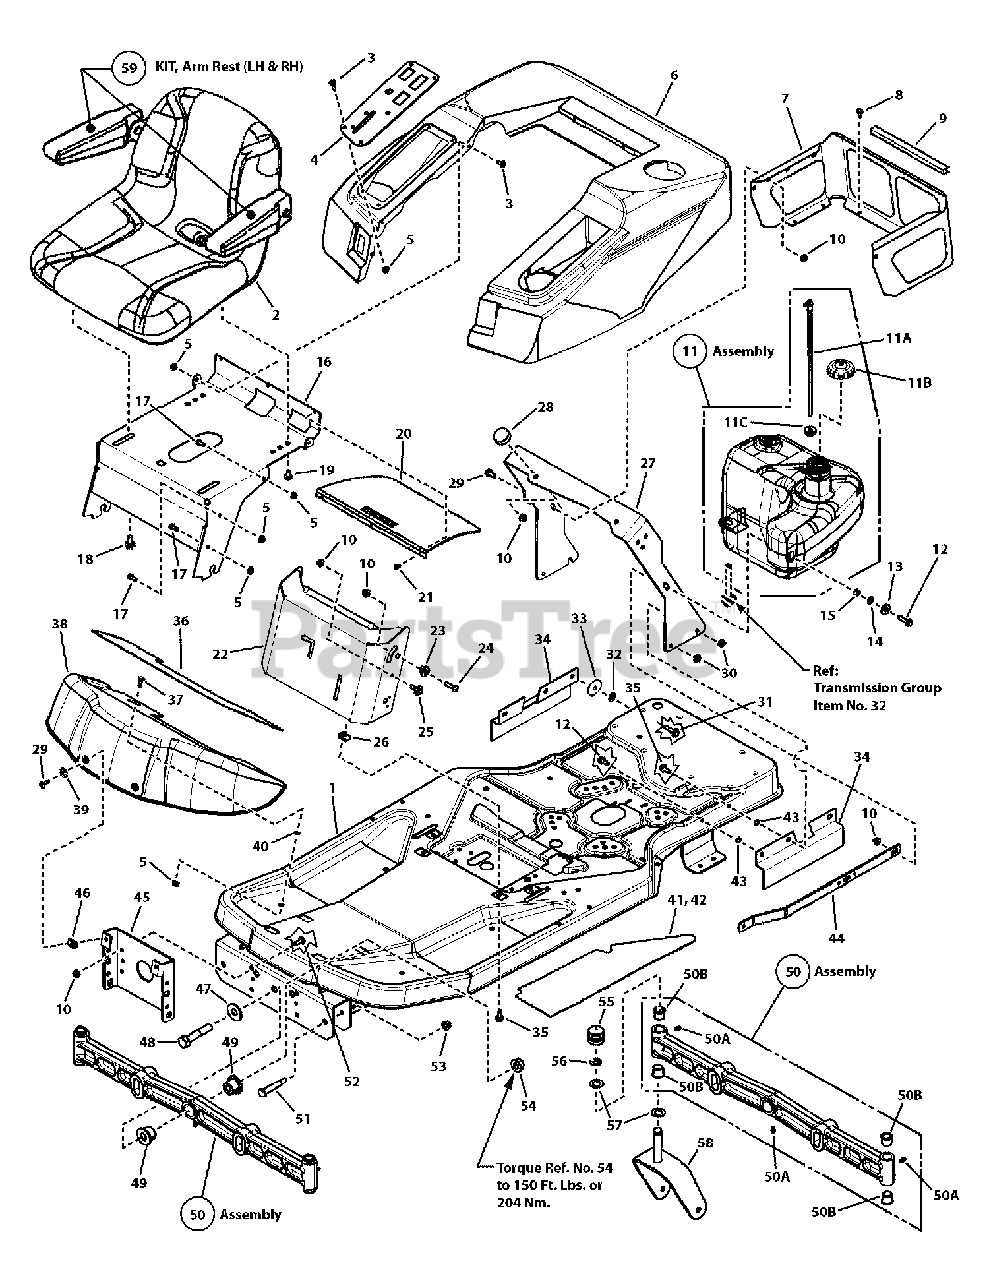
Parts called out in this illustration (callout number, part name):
1	WELDMENT, ZT Frame
2	ASSEMBLY, Seat w/Arm Rests, ZTR
3	SCREW, 1/4-20 x 3/4" Truss Head Torx, Black
4	PLATE, Control, Choke-A-Matic
5	NUT, 1/4-20 Hex Flange Nyloc, Black
6	SEAT DECK, Red Poly, ZTS - Red
7	BRACKET, Rear Shroud, ZTR, Black
8	SCREW, 1/4-20 x 1/2" Hex Washer Head Screw Black (Taptite)
9	TRIM, 8"
10	NUT, 5/16-18 Hex Flange Lock, Small - Black
11	ASSEMBLY, Fuel Tank (incl. Items 11A, 11B & 11C)
11A	ASSEMBLY, Elbow/Pick-up Tube
11B	ASSEMBLY, Fuel Cap (Vented)
11C	BUSHING, Fuel
12	SCREW, 5/16-18 x 1-1/4" Hex Head Cap, GR5, Black
13	WASHER, 5/16" Flat (.341 I.D. x 1.00 O.D. x .13 Thick) Black
14	WASHER, 5/16" Internal/External Tooth Lock, BZ
15	SPACER, .316 x .375 x .300/.310
16	SUPPORT, Seat
17	SCREW, 1/4-20 x 3/4" Hex Whiz Lock Flange
18	BOLT, 5/16-18 Shoulder
19	SCREW, 5/16-18 x 3/4" Hex Flange Lock Dog Point
20	SCREEN, Deck Top
21	RIVET, .188 x .617 Large Flange
22	PANEL, Front - Manual Brake & Deck Lift
23	PIVOT, Hood (Powdered Metal)
24	BOLT, 5/16-18 x 1-1/4" Round Head Short Square Neck GR5, Black
25	SHOULDER BOLT, 5/16-18
26	NUT, Speed, Lug Type, 5/16-18
27	SUPPORT, Seat Deck
28	BUMPER, Rubber 1.50 DIA 0.5 Thick
29	SCREW, 5/16-18 x 1" Hex Head Cap
30	NUT, 5/16-18 Hex Flange Nyloc
31	SCREW, 3/8-16 x 1-1/4" Hex Head Cap, GR5, Black
32	PUSH NUT, .375 Dia. Thread .781 O.D., Black (Pal)
33	WASHER, .375 Flat (0.41 I.D. x 1.50 O.D. x .25 Thick) Black
34	GUARD, Debris, ZTR - Black
35	BOLT, 5/16-18 x 1" Hex Flange Lock YZ
36	PAD, Footrest Center Black Vinyl
37	BOLT, 1/4-20 x 2" Round Head Short Square Neck, GR5, Black
38	PANEL, Footrest, 18 Ga ZT 7000, Red
39	WASHER, 5/16" External Tooth Lock Washer, Yellow
40	RETAINER, 1/4" Bolt
41	PAD, Footrest RH Black Vinyl w/Adhesive
42	PAD, Footrest LH Black Vinyl w/Adhesive
43	PUSH NUT, 5/16" Dia. Thread .625 O.D. Black (Pal)
44	STRAP, Fuel Tank Brace
45	BRACKET, Footrest Support, Black
46	SPEED NUT, 1/4-20 Lug Type .025/.150, Black
47	WASHER, 0.64 I.D. x 1.75 O.D. x .11 Thick, Black
48	SCREW, 5/8-11 x 3-1/4" Hex Head Cap, GR5, Yellow
49	BUSHING, Axle Pivot PM, Yellow
50	ASSEMBLY, AXLE, Front Iron Casting Machined ZT (Incl. Items 50A & 50B)
50A	LUBE FITTING, .250 Drive Type
50B	BUSHING
51	SHOULDER BOLT, 3/8-16 x 3" Long .50 Sh GR5, Black
52	BOLT, 5/16-18 x 7/8" Round Head Short Square Neck Carriage, GR5
53	NUT, 3/8-16 Hex Flange Nyloc
54	NUT, Hex Flange 5/8-11 Two Way Lock, Yellow
55	CAP, Hub 1.481 I.D. x .62 Long Red Poly
56	KLIPRING, External for .750 Dia. Shaft
57	WASHER, .75 ID x 1.60 OD x .05 Thick Flat (Black)
58	WELDMENT, Caster Yoke & Spindle - Black
59	KIT, Arm Rest L.H. & R.H.
